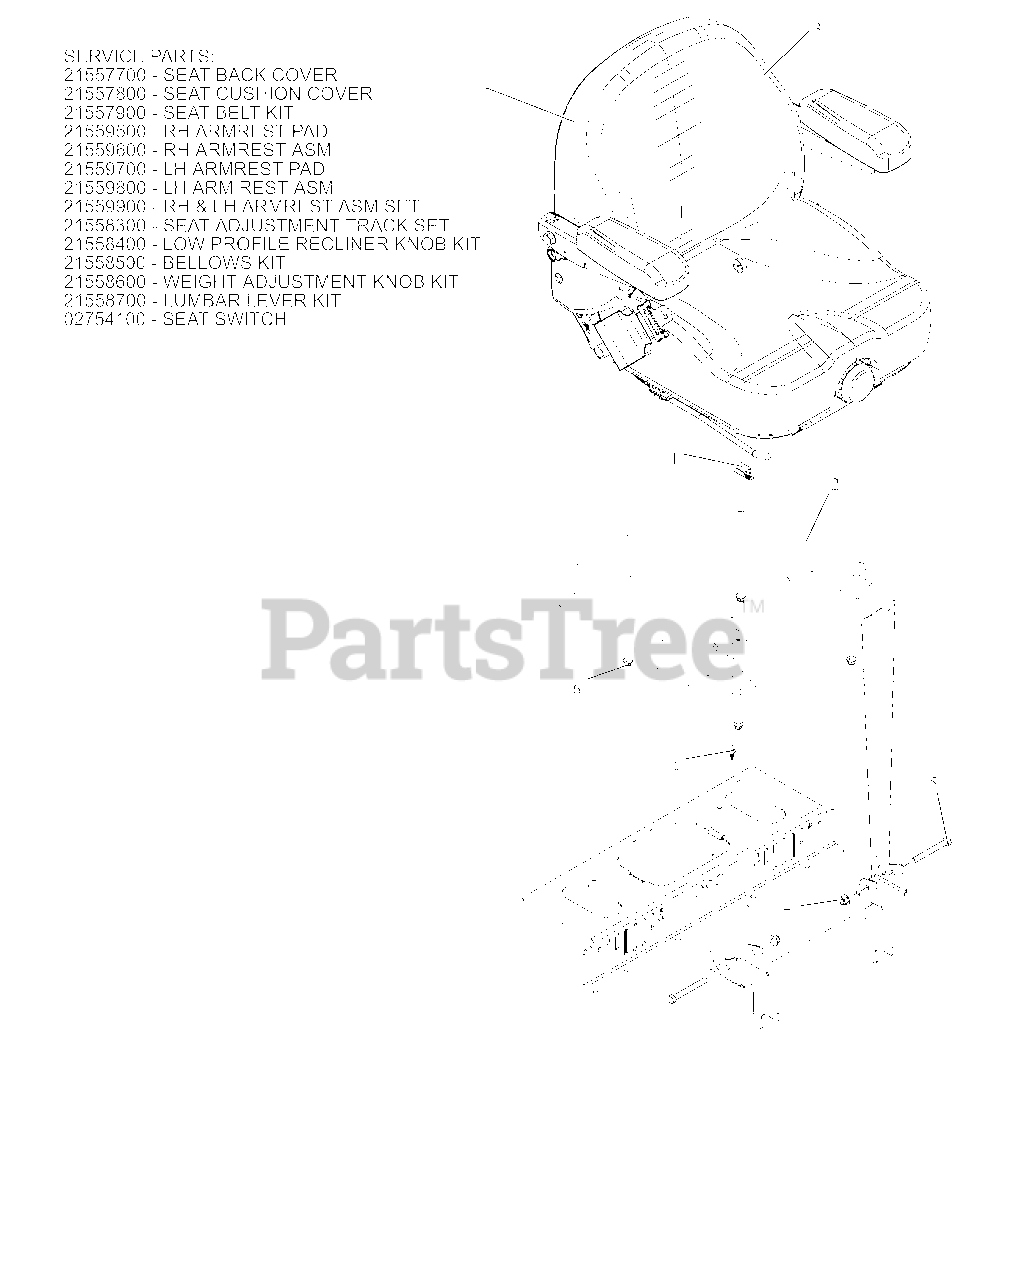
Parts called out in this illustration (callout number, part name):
1	HARNESS, PT200 SEAT ADAPTER
2	WLDMT, SEAT PLATE (RED)
3	SEAT, FULL SUSPENSION
3	COVER, SEAT BACK
3	COVER,SEAT CUSHION
3	KIT, SEAT BELT
3	PAD, RH ARMREST
3	ASM, RH ARMREST
3	PAD, LH ARMREST
3	ASM LH ARMREST
3	SET, RH & LH ARMREST ASM
3	SET, SEAT ADJUSTMENT TRACK
3	KIT, LOW PROFILE RECLINER KNOB
3	KIT, BELLOWS
3	KIT, WEIGHT ADJUSTMENT KNOB
3	KIT, LUMBAR LEVER
3	SWITCH- SNAP MTG N.O.
4	CABLE TIE W/ TREE (.25 HOLE)
5	BLT, HEX .38-16X3.25 G5 ZCC
6	NUT,NYL-FLG .31-18 GF ZCC
7	NUT,NYL-FLG .38-16 GF ZCC
